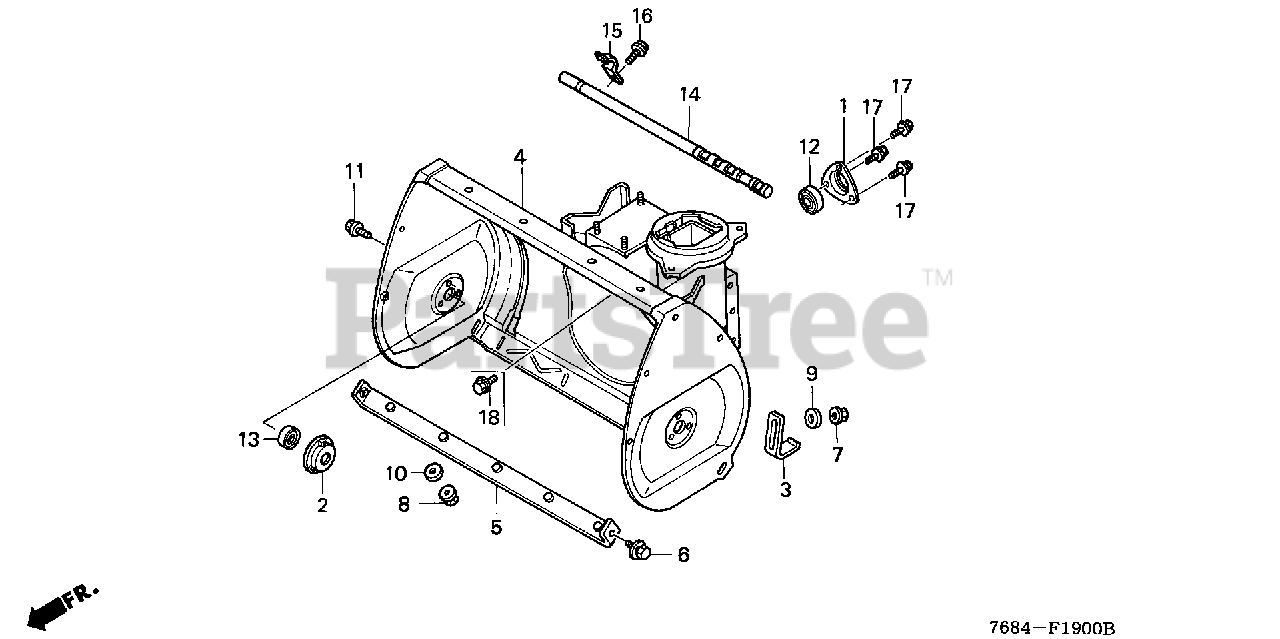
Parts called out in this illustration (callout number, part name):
1	HOLDER, WHEEL SHAFT BEARING
2	HOLDER, AUGER BEARING
3	SKID, AUGER
4	HOUSING, AUGER
5	GUARD, AUGER HOUSING
6	BOLT-WASHER (8X16)
7	NUT, FLANGE (6MM)
8	NUT, FLANGE (8MM)
9	WASHER, PLAIN (6MM)
10	WASHER, PLAIN (8MM)
11	BOLT, FLANGE (6X12)
12	BEARING, RADIAL BALL (6004UU)
13	BEARING, RADIAL BALL (6203UU)
17	BOLT, FLANGE (6X12)
